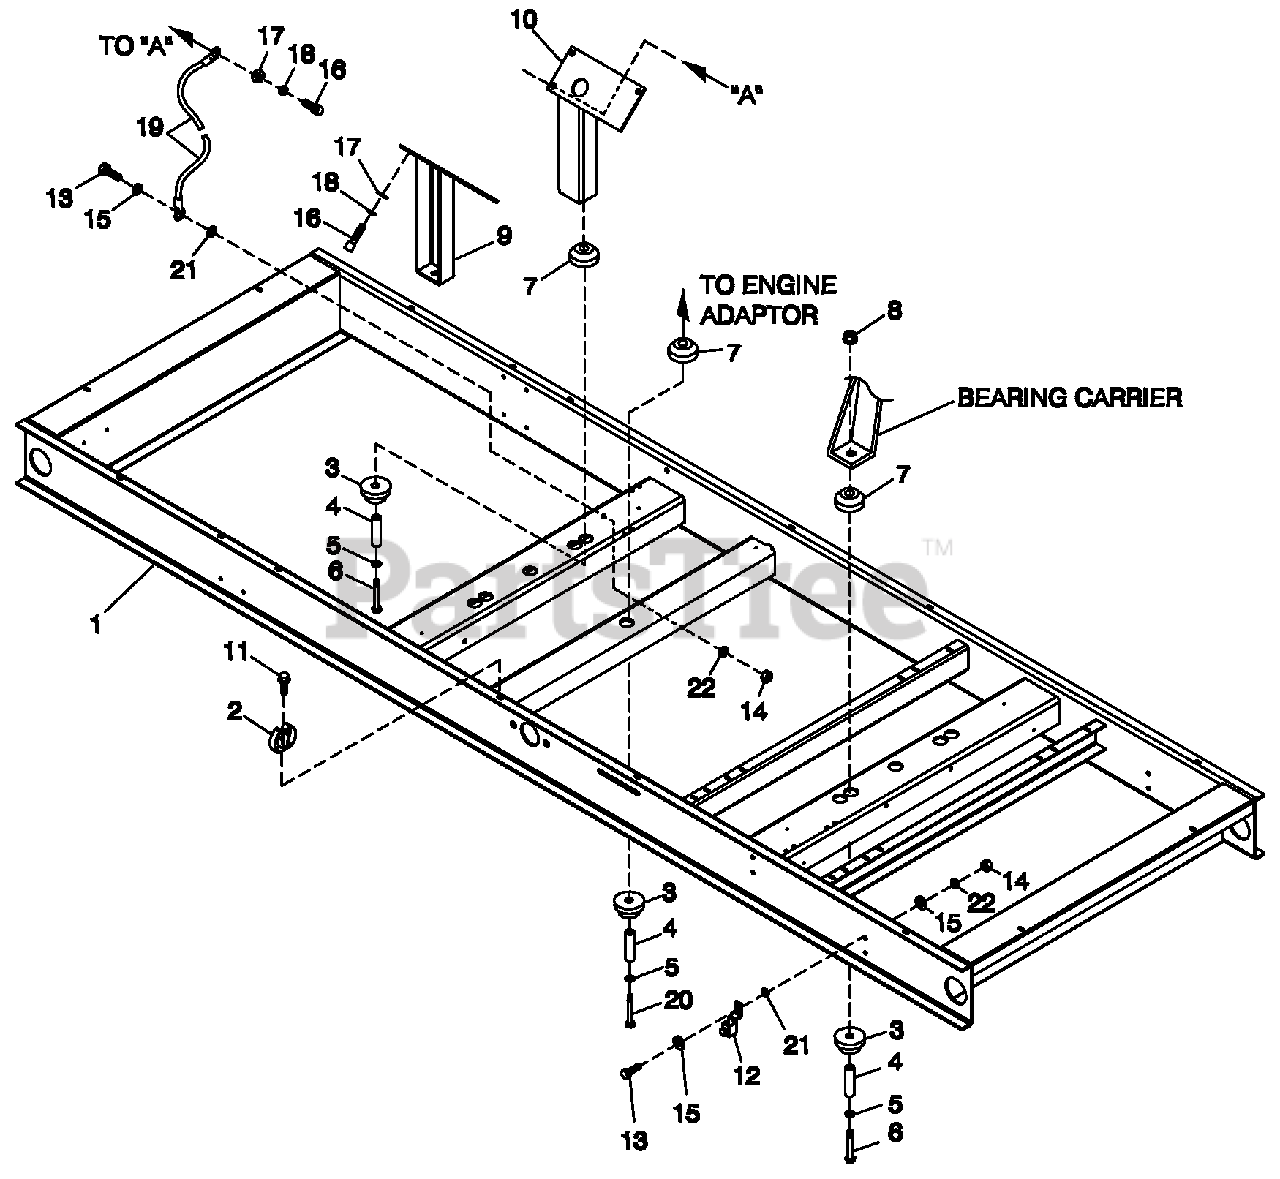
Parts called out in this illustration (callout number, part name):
1	MTG BASE C5 4.6/80KW 5.4/100KW
2	SPRING CLIP HOLDER .37-.62
3	DAMPENER VIBRATION
4	SPACER .49 X .62 X 1.87 PWDR/ZINC
5	WASHER FLAT M12
6	SCREW HHC M12-1.75 X 85 G8.8
7	DAMPENER VIBRATION 50 WHITE
8	NUT LOCKING M12-1.75
9	SUPPORT ENG 4.6L LH
10	SUPPORT ENG 4.6L RH
11	SCREW HHTT M4-0.7 X 8 BP
12	LUG SOLDERLESS 3/0-#4 X 13/32 CU
13	SCREW HHC M6-1.0 X 25 G8.8
14	NUT HEX M6 X 1.0 G8 YEL CHR
15	WASHER FLAT 1/4-M6 ZINC
16	SCREW SHC M10-1.5 X 30 G12.9
17	WASHER FLAT 3/8-M10 ZINC
18	WASHER LOCK M10
19	ASSY WIRE 14.00"
20	SCREW HHC M12-1.75 X 80 G10.9
21	WASHER SHAKEPROOF EXT 5/16 STL
22	WASHER LOCK M6-1/4
